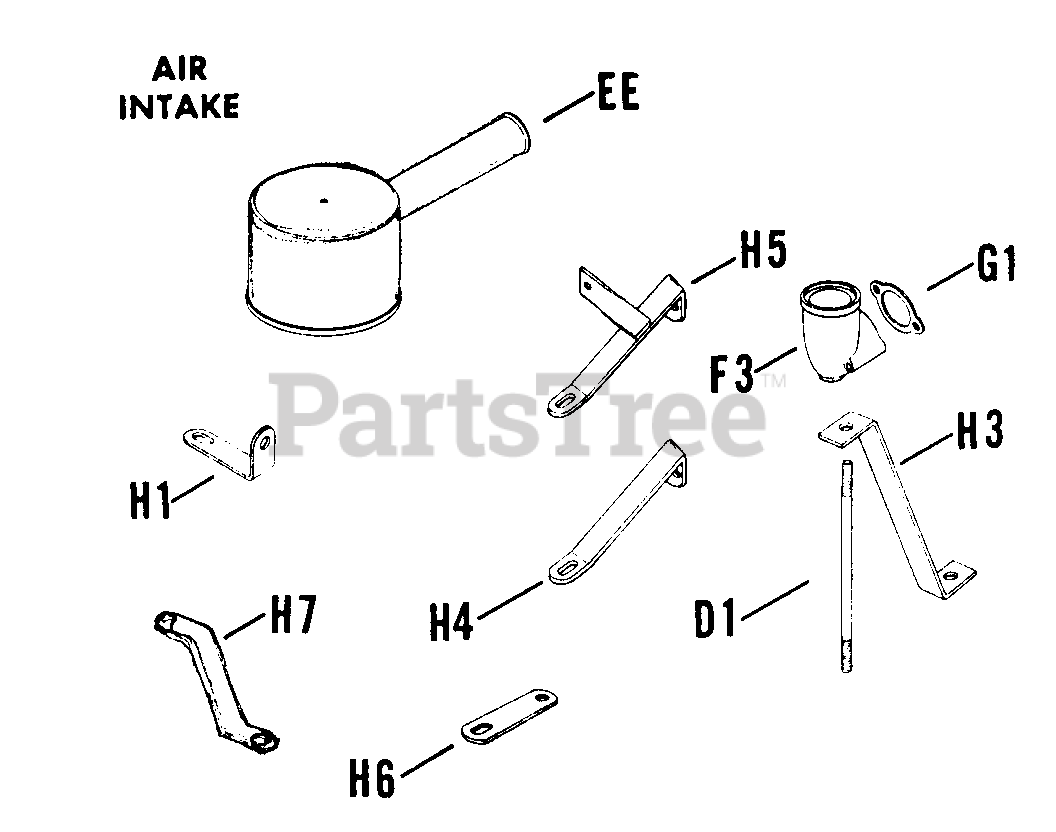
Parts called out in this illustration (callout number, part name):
D1	STUD,1/4-20x6-1/4" - DISC.
G1	GASKET - USE 41 041 11
H1	BRACE - DISCONTINUED
